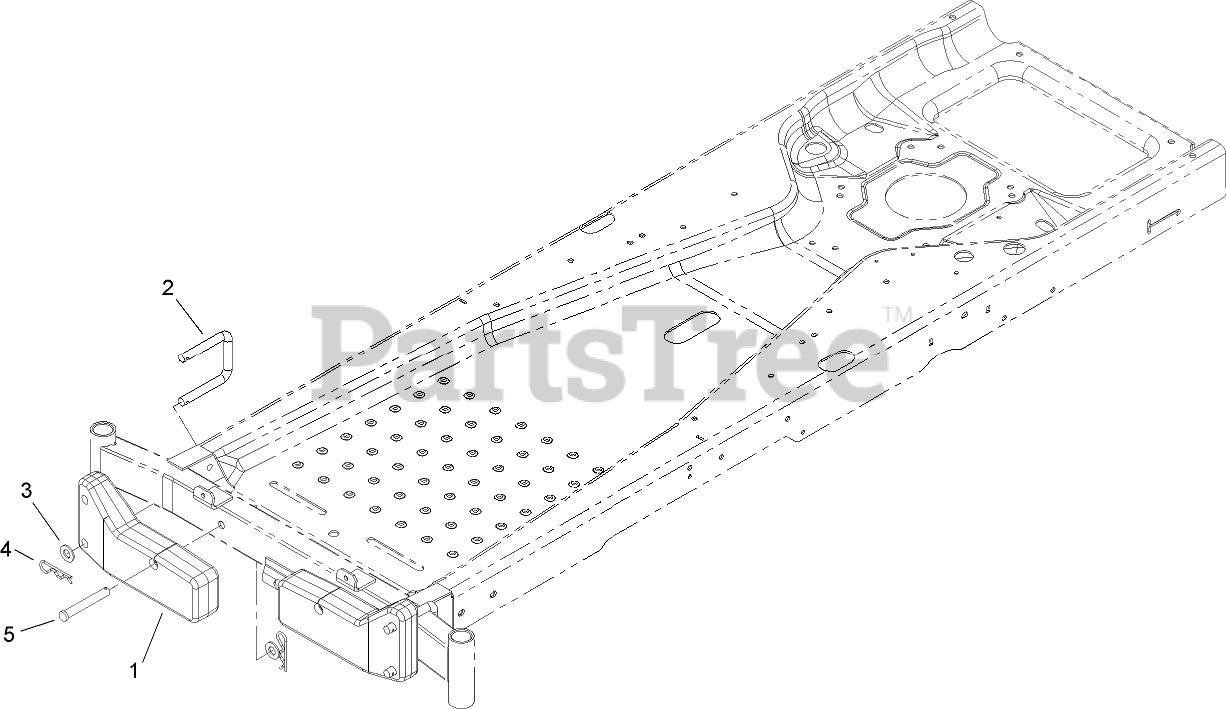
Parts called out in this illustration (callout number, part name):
1	WEIGHT-BAGGER
2	PIN-WEIGHT, BAGGER
3	WASHER-FLAT
4	PIN-HAIR
5	PIN-CLEVIS
